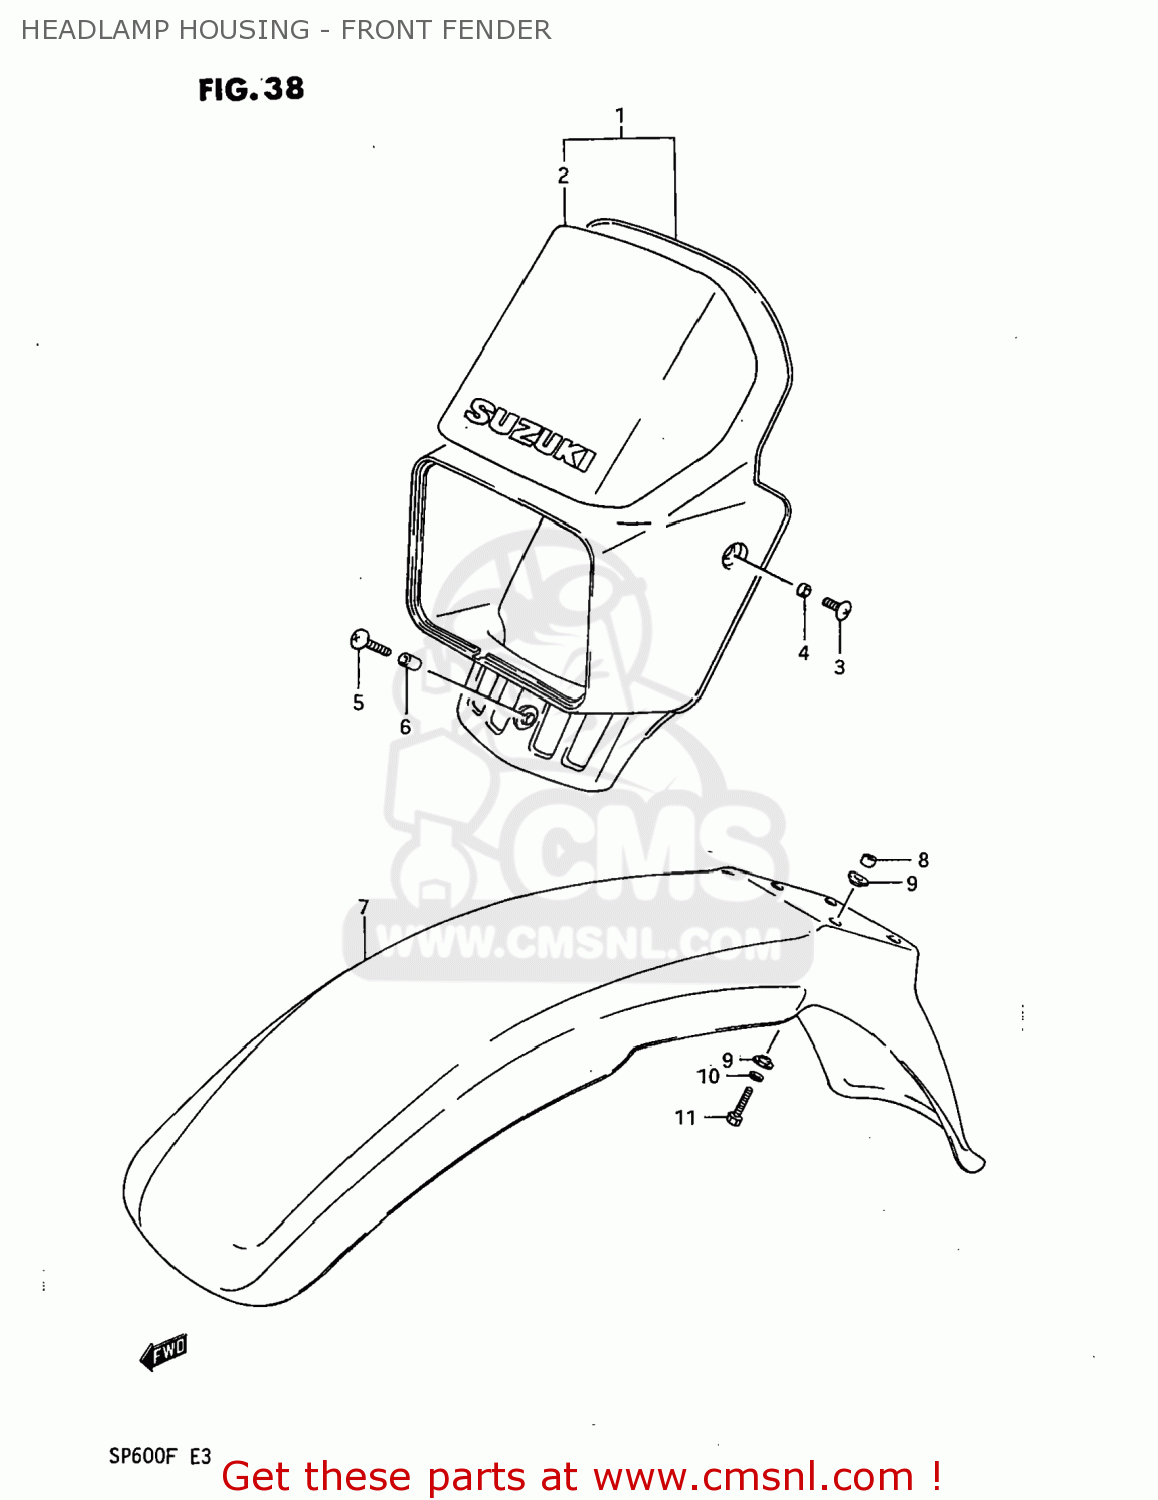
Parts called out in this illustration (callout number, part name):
1	COVER,HEADLAMP
2	TAPE SET,HEADLAMP COVER
3	SCREW 6X12
4	SPACER (6.1X8X3.5)
5	SCREW, CENTER
6	SPACER (6.1X8X12)
7	FENDER,FR
8	SPACER(6.1X9X7.5)
9	SPACER
10	LOCK WASHER
11	BOLT
